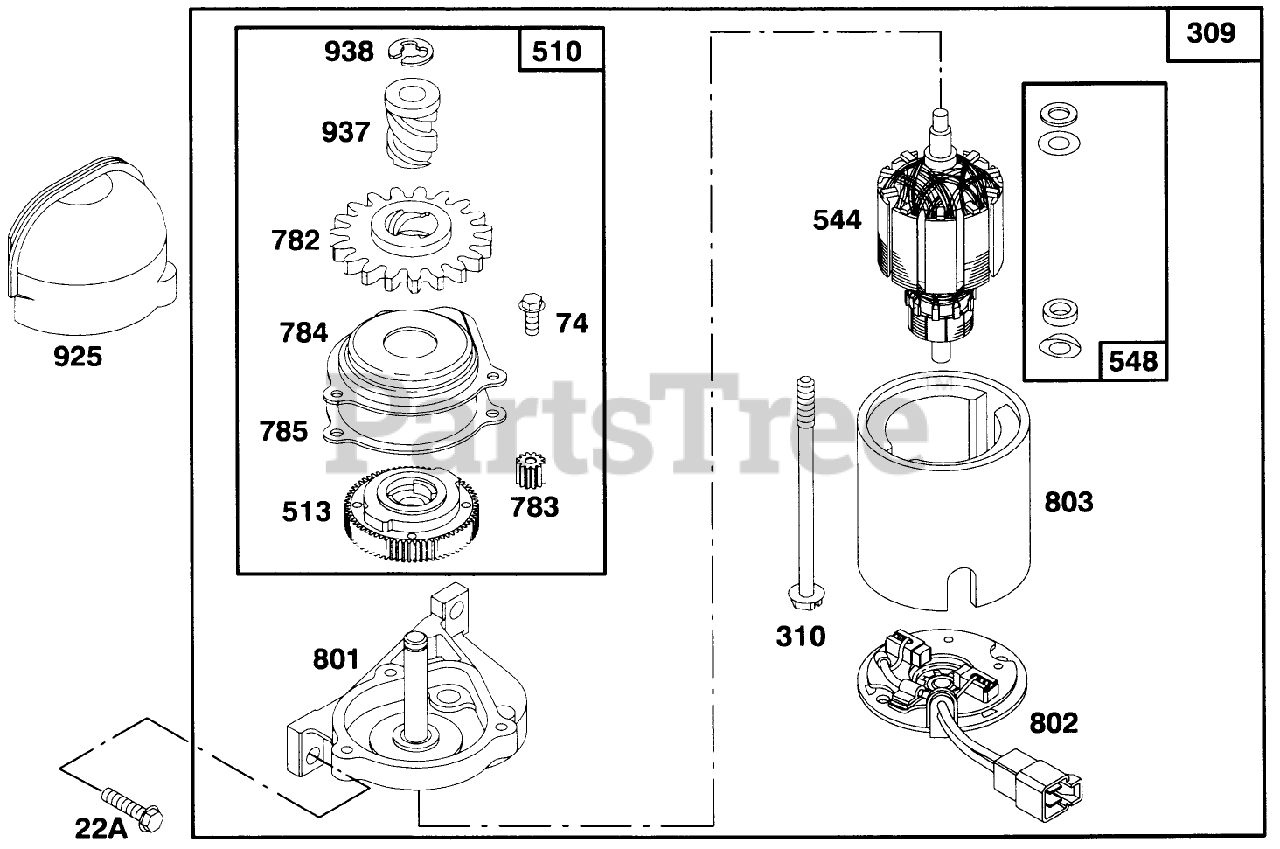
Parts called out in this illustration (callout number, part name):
22A	SCREW - CARBUERTOR MTG
510	DRIVE SET
513	CLUTCH - STARTER
548	WASHER ASSEMBLY
782	GEAR - STARTER
925	COVER - STARTER
938	RETAINER - LOCK
